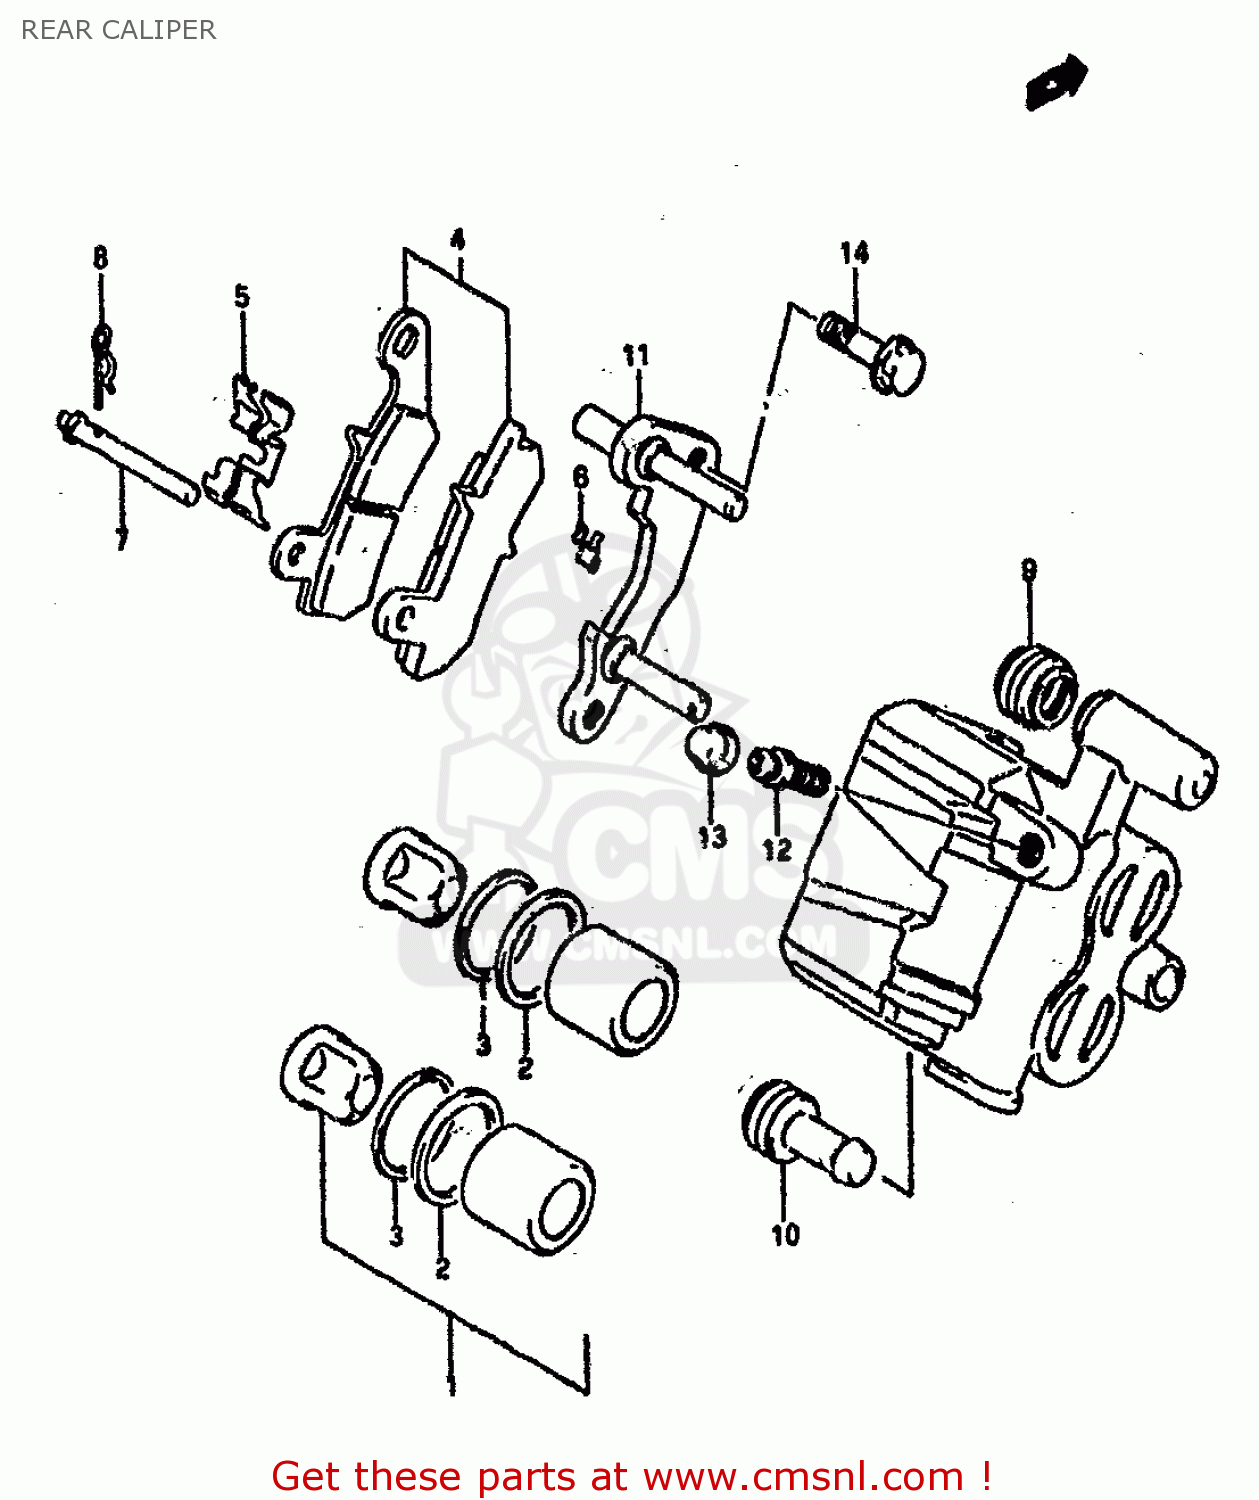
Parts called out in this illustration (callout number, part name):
1	BRAKE PISTON SET
2	SEAL,PISTON
3	SEAL,WIPER
4	PAD SET (NAS)
5	SPRING,PAD
6	GUIDE,PAD
7	PIN,PAD
8	CLIP,PAD PIN
9	BOOT,AXLE
10	INSULATOR,AXLE
11	CARRIER
12	BLEEDER
13	CAP,BREATHER
14	BOLT(8X22)
